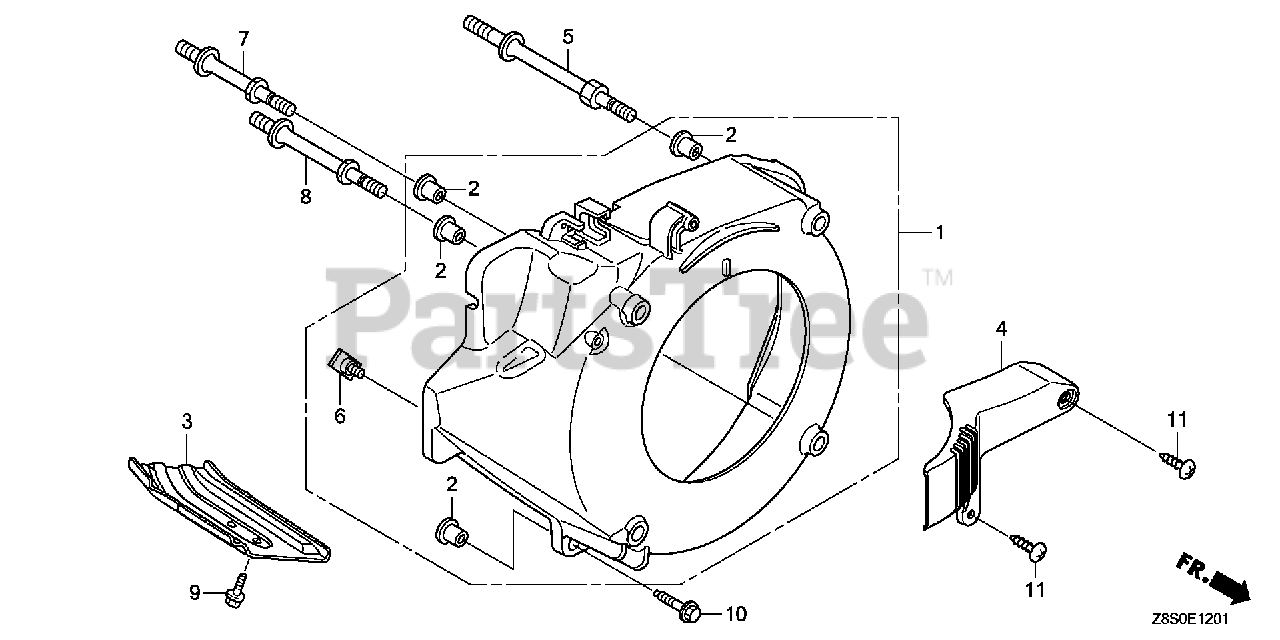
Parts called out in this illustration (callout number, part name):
1	COVER, FAN *NH1* (BLACK)
1	COVER, FAN *R280* (POWER RED)
2	COLLAR, FAN COVER
4	COVER, ELECTRONIC PARTS
5	BOLT, STUD (SEL)
6	BOLT, SPECIAL (6MM)
7	BOLT, STUD
8	BOLT B, STUD
9	BOLT, FLANGE (6X12) (CT200)
10	BOLT, FLANGE (6X25) (CT200)
11	SCREW, TAPPING (5X20)
